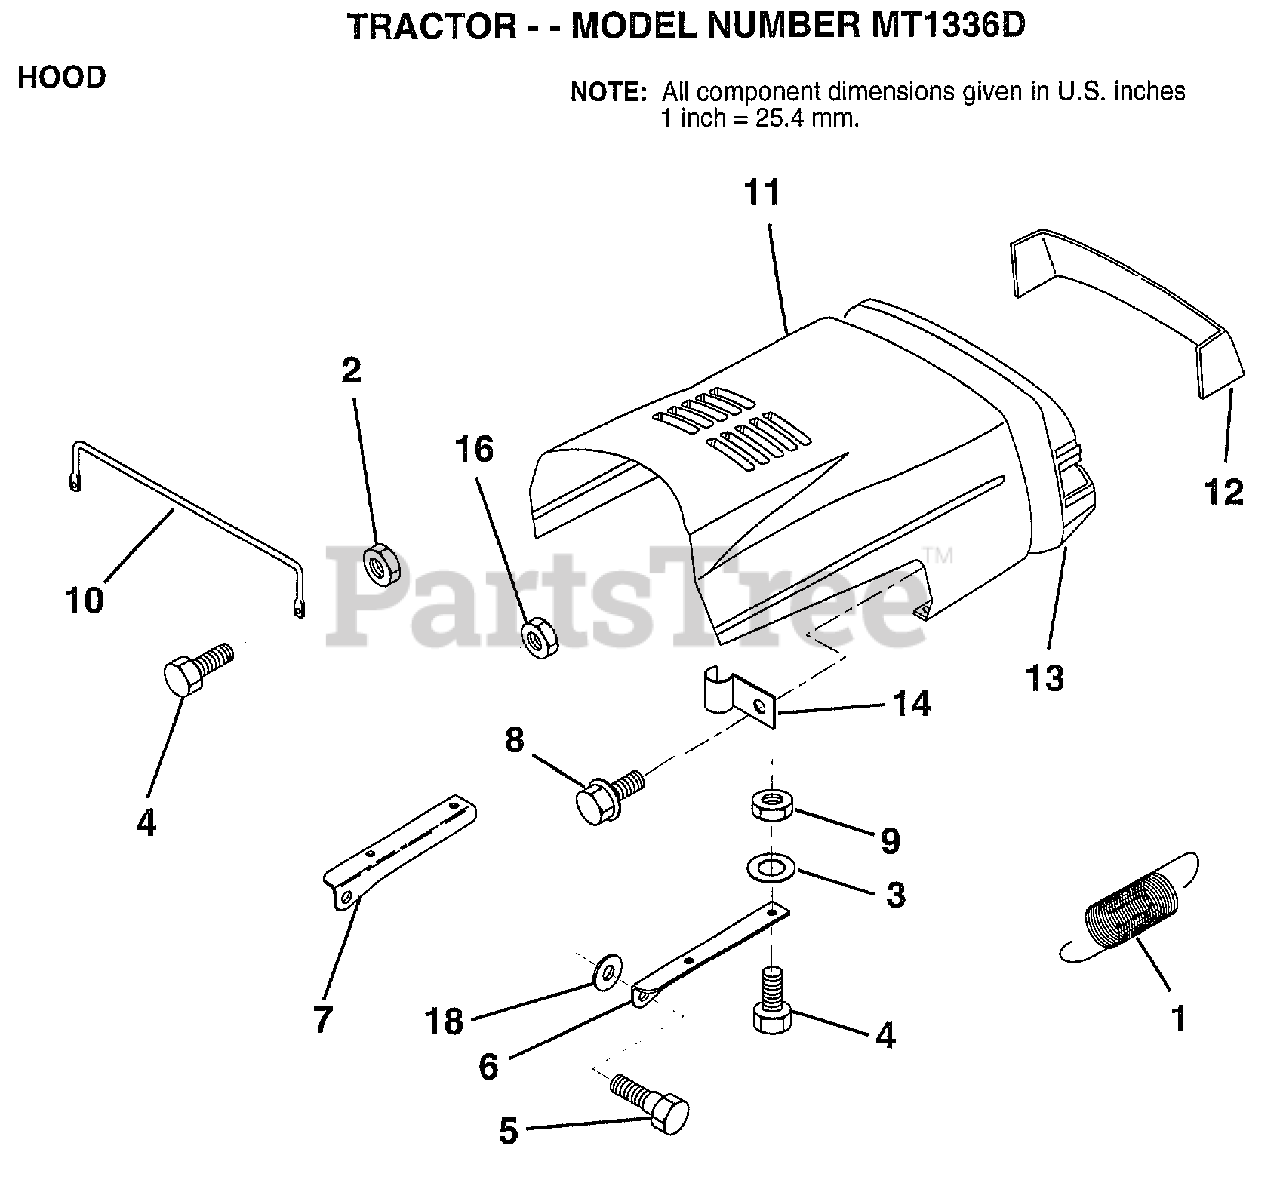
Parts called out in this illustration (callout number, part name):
1	EXT SPRING
2	NUT
3	WASHER
5	BOLT.SHLD.5/16-18
6	BRKT HOOD RH
7	BRKT HOOD LH
8	"SCREW,HWHD.HI-LO#13-16X3/4"
9	NUT
10	"BRACE,HOOD"
11	HOOD
12	LENS.BAR.CLEAR.LR
13	GRILL
16	NUT
18	WASHER
